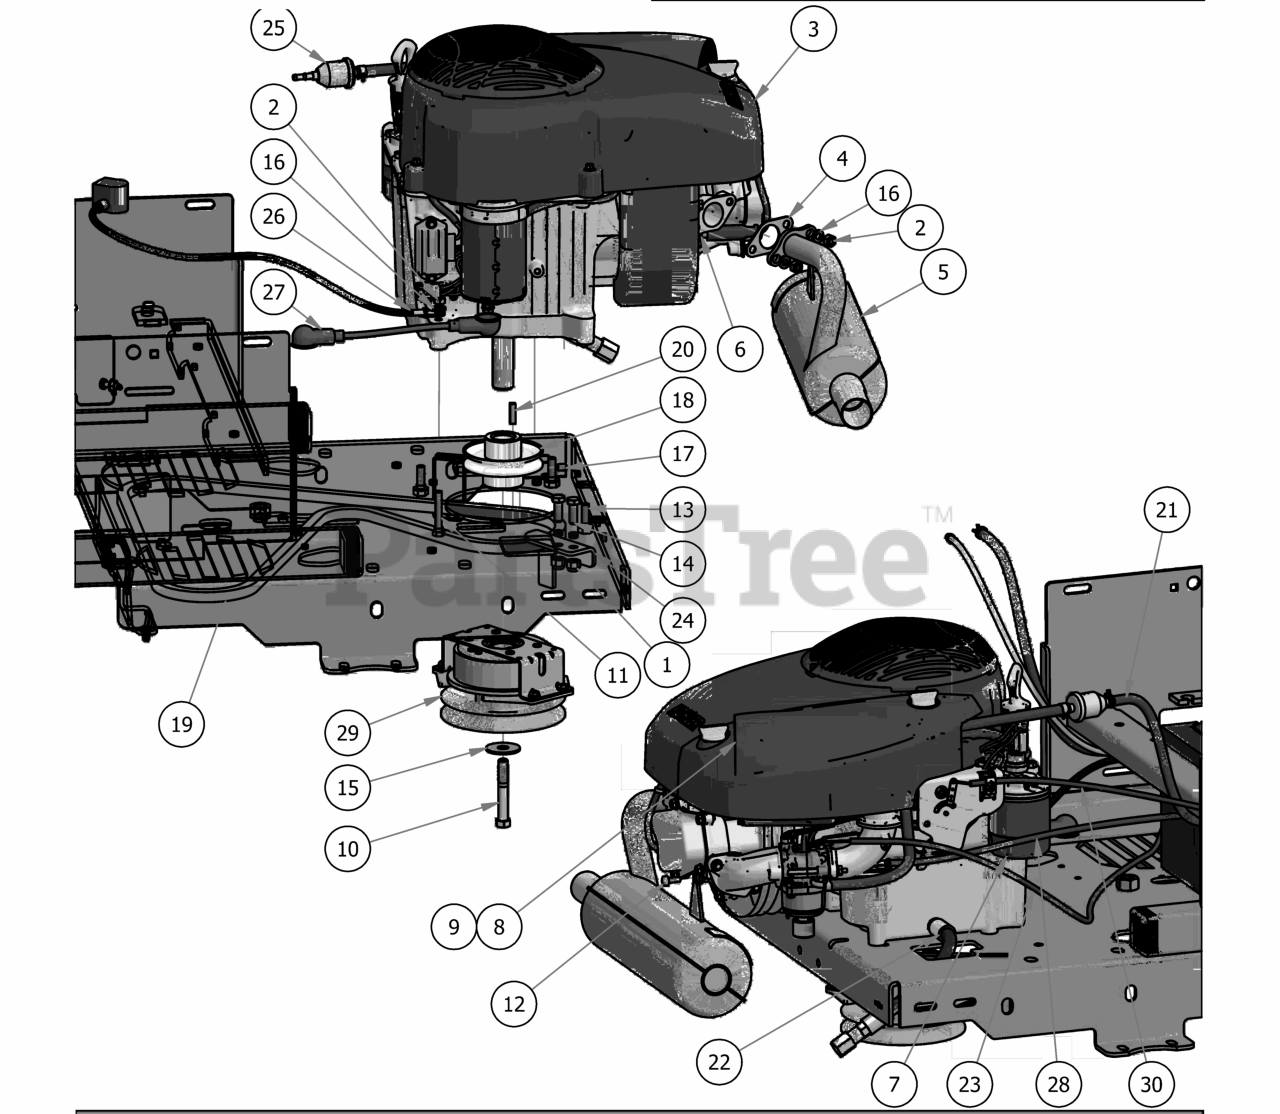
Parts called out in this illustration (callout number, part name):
1	3/8 Nylock Nut
3	Kohler KS-590 541cc 19Hp
4	Exhaust Gasket
5	Kohler KS-590 Muffler
6	Kohler KS-590 Spark Plug
7	Kohler KS-590 Oil Filter
8	Kohler KS-590 Air Pre-Cleaner
9	Kohler KS-590 Air Filter
10	7/16"-20 x 3" Hex Bolt Gr. 8
11	5/16-18 X 2 Hex C/S (GR.5) ZC
12	M6-1.0x16mm Self-Tapping Bolt
13	3/8 x 1 1/8 bolt
14	3/8" x 1" Hex Bolt
15	1/2" Belleville Washer
16	5/16" Lock Washer
17	3/8" Set Screw
18	3-3/4" Motor Pulley
20	1/4" x 1" Key
21	37" Fuel Line Assembly
22	Oil drain Hose
24	2017 MZ Clutch Stop
25	Universal In-line Fuel Filter
26	Ground Cable
27	12" Red Battery Cable
28	MZ Kohler EPA Canister Assembly
30	2017 MZ Control Panel Assembly
